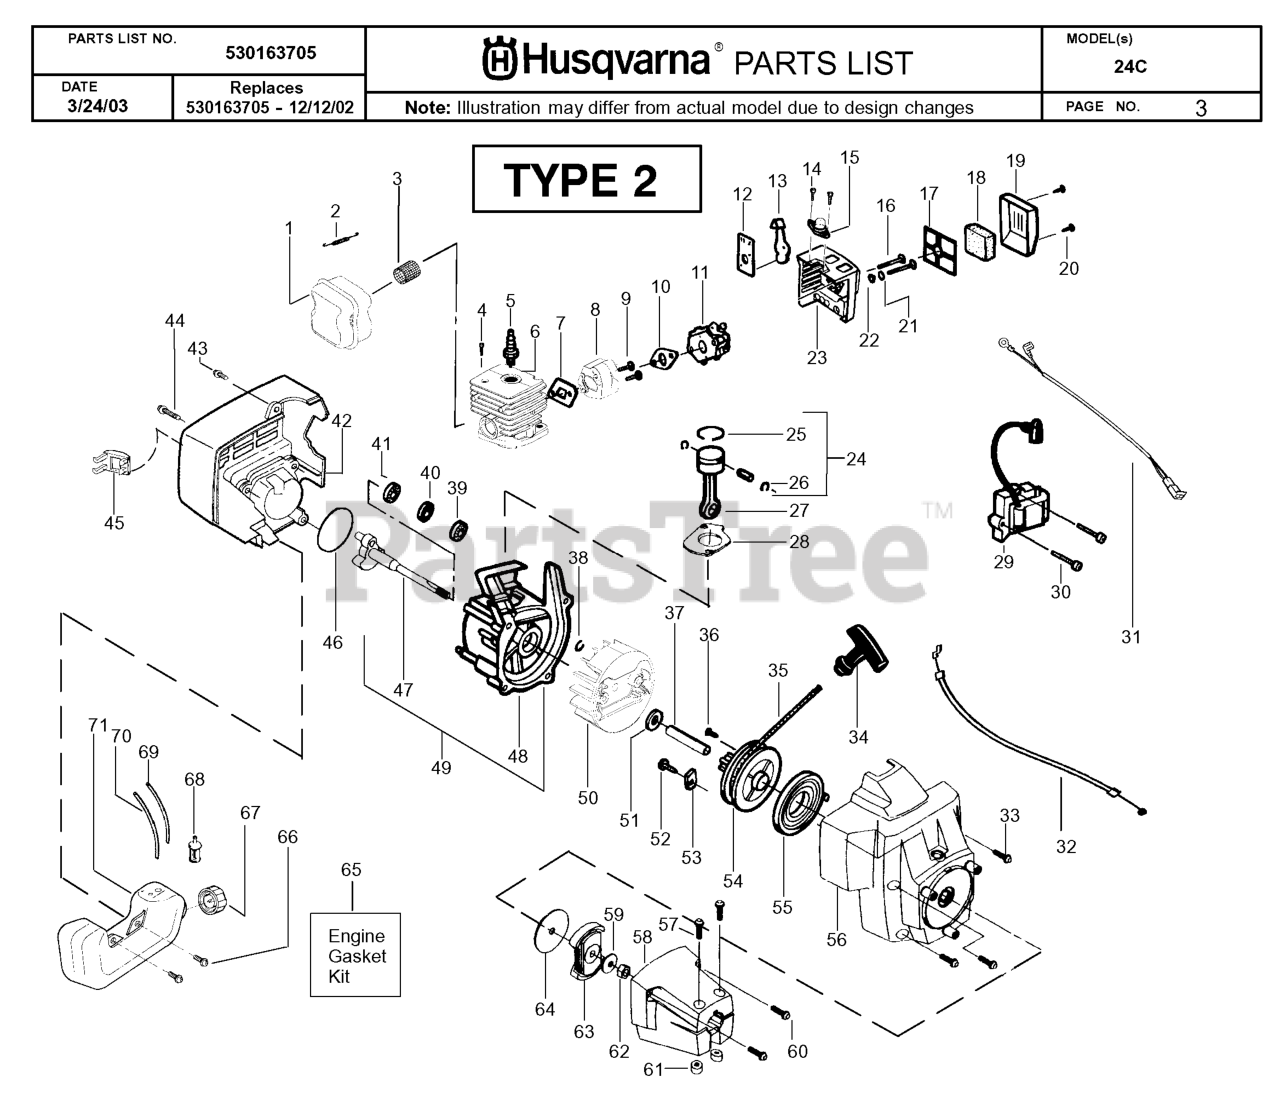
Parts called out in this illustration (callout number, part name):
1	KIT-MUFFLER
2	SPRING-MUFFLER (NEW STYLE)
7	GASKET KIT
8	ADAPTER
9	SCREW - CARB. ADAPTOR
10	GASKET KIT
11	CARBURETOR
12	CHOKE PLATE
13	CHOKE SHUTTER
14	SCREW 6-19X5/8 PLAS.PAN
15	AIR PURGE BUBBLE
16	SCREW 10-10 X 2.150 TC
17	FILTER PLATE
18	AIR FILTER FOAM
19	AIR FILTER COVER
20	SCREW FILTER PLATE
21	CHOKE SPACER
23	FILTER HOLDER
24	PISTON
25	PISTON RING
26	WRIST PIN RET.
27	KIT-CONN ROD ASSY
28	GASKET KIT
29	IGNITION MODULE
31	LEAD WIRE ASSEMBLY
32	THROTTLE WIRE
33	SCREW - SHROUD
34	STARTER HANDLE
38	RETAINING RING
39	OUTER BEARING
40	KIT-CRANKCASE SEAL
42	SHROUD HUSQ ORANGE
44	SCREW - SHROUD
46	GASKET KIT
47	ASSY-CRANKSHAFT
48	KIT ASSY CRANKCASE
49	KIT ASSY C'CASE/C'SHAFT
50	FLYWHEEL
52	SCREW 8-16 X 9/16 (PLAS
54	STARTER PULLEY KIT
55	STARTER SPRING
57	SCREW-10-24 X 1-3/8 (UN
58	ASSY CLUTCH HSG HUSKY
59	WASHER FLAT
60	SCREW-10-14 X 13/16 (PL
61	LOCKNUT-HEX 10-24
63	CLUTCH ASSEMBLY KIT
64	FRICTION DISC,CLUTCH 36/41
65	GASKET KIT
68	FUEL PICK-UP ASSY
69	KIT.LINE TANK/PURGE
70	HOSE. FUEL
